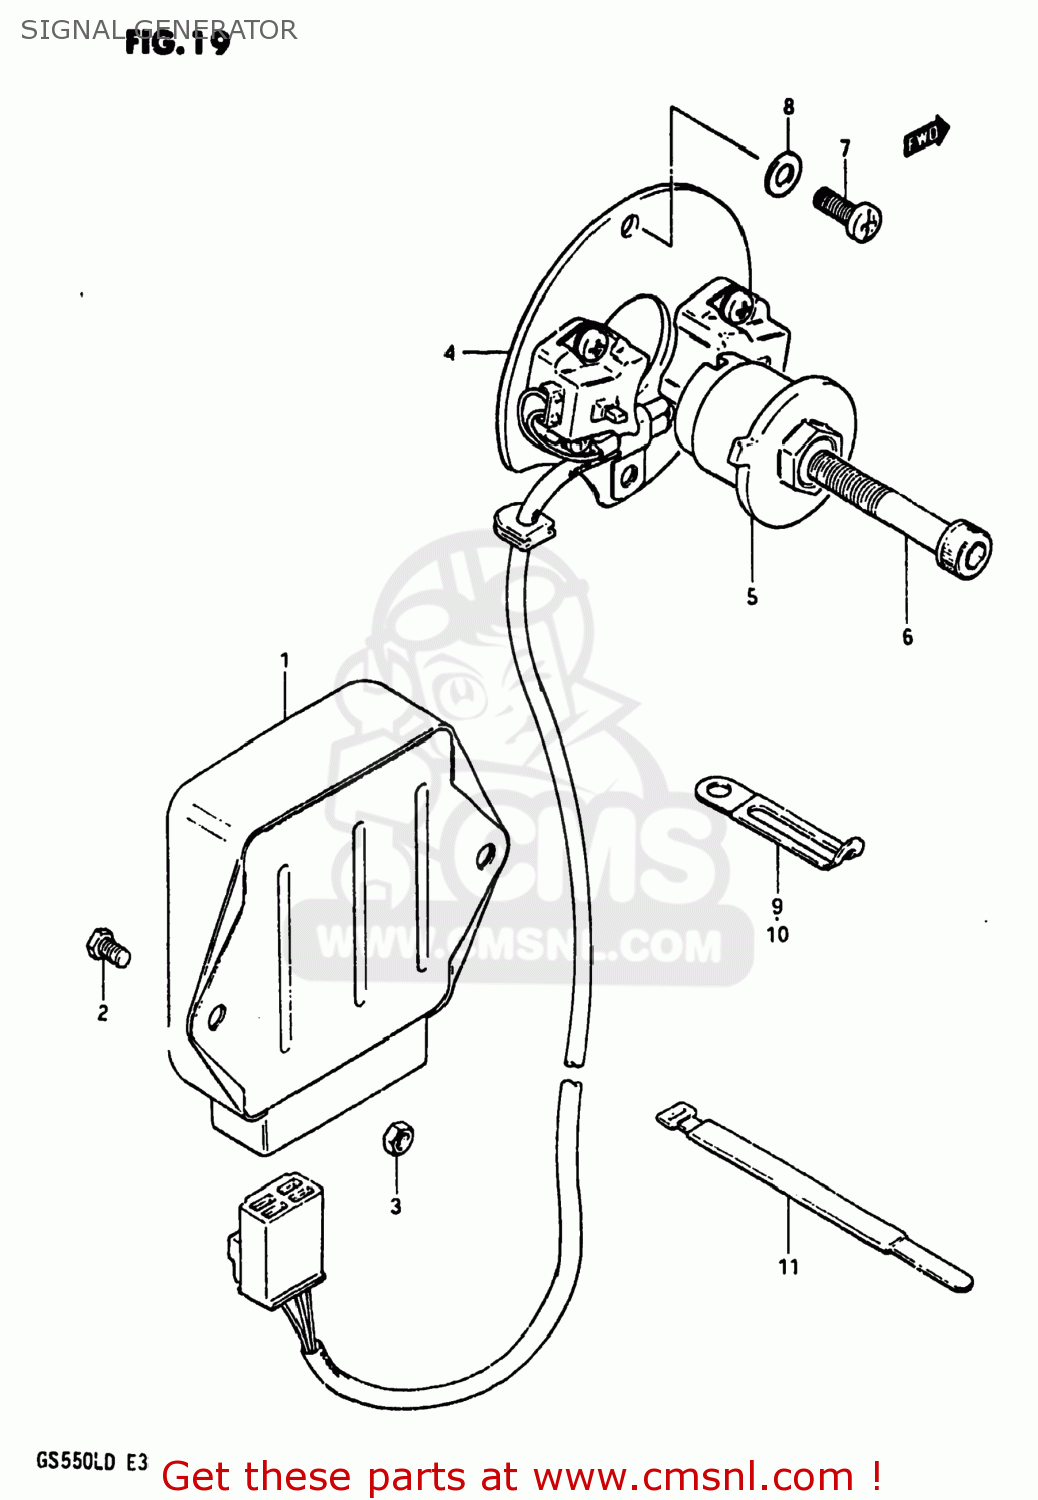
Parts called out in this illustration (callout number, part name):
1	IGNITER UNIT ASSEMBLY
3	NUT
4	GENERATOR ASSY,SIGNAL
5	ROTOR,SIGNAL
6	BOLT
7	SCREW(5X12)
8	WASHER
9	CLAMP L:35
10	CLAMP
11	CLAMP
